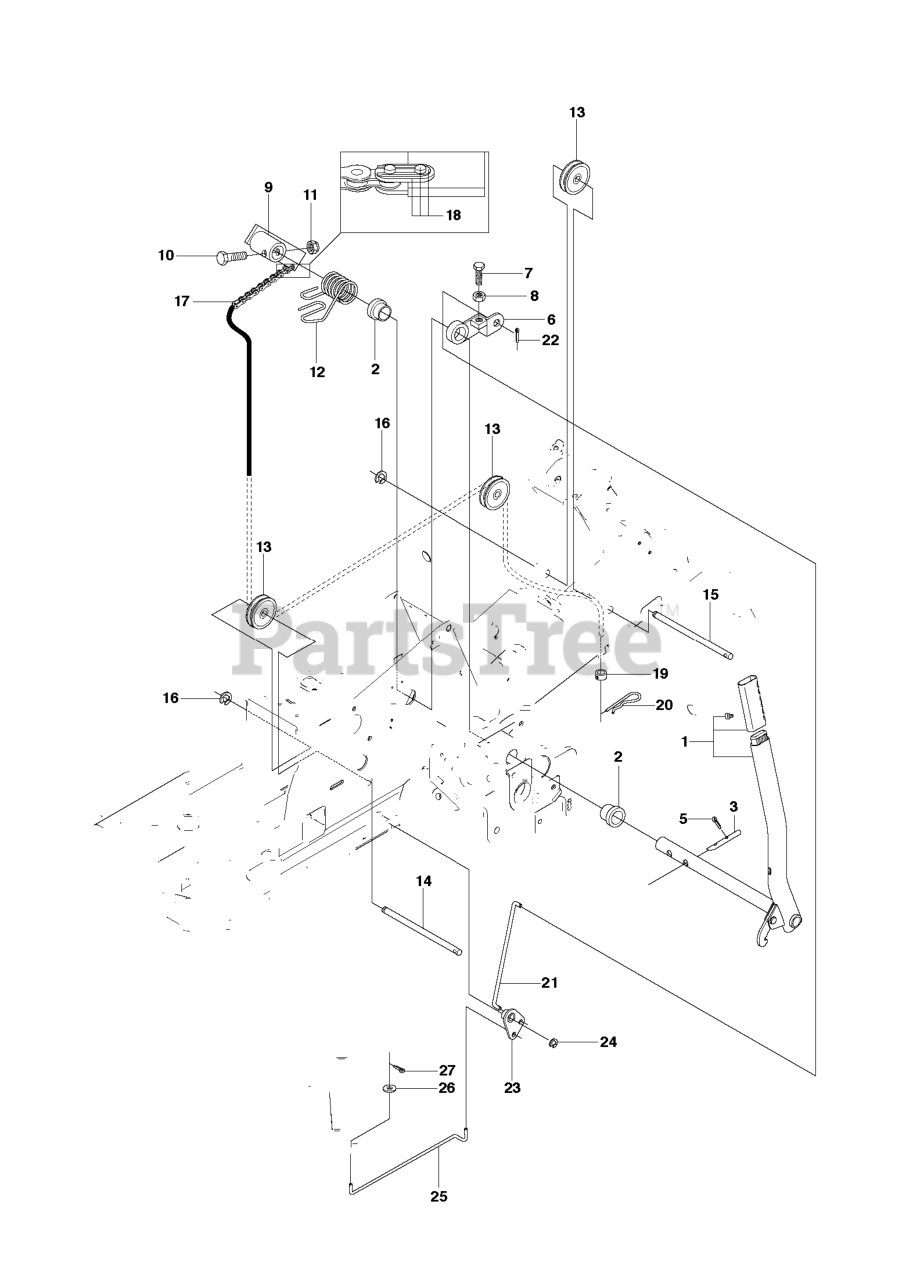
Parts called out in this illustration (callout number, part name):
1	LIFTING LEVER ASSY
2	BEARING FLANGE
6	LEVER CLUTCH
8	NUT
9	LIFTING ARM
21	CONNECTION ROD
24	RETAINING RING
25	CONNECTION ROD
